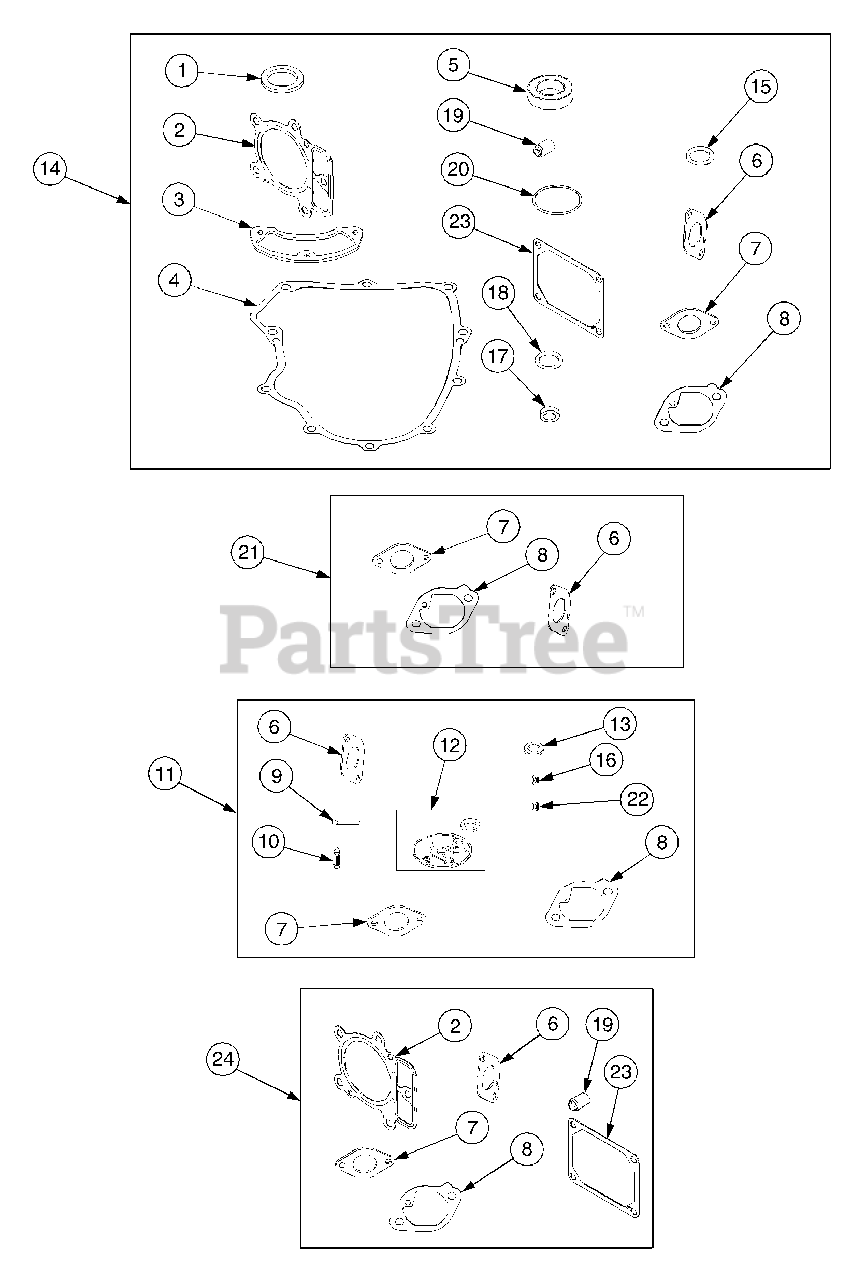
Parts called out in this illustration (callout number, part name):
1	Seal, Oil
2	Gasket, Cylinder Head
3	Gasket, Breather
4	Gasket, Crankcase
5	Seal, Oil
6	Gasket, Intake
7	Gasket, Intake
8	Gasket, Intake
9	Pin, Float Hinge
10	Valve, Float Needle
11	Kit, Carburetor Overhaul
12	Gasket, Float Bowl
13	Washer, Sealing
14	Set, Engine Gasket
15	Seal, Dipstick Tube
16	Seal, Choke/Throttle Shaft
17	Seal, Governor Shaft
18	Seal, Dipstick/Tube
19	Seal, Valve
20	Seal, O-Ring
21	Gasket Set, Carburetor
22	Seal, Throttle Shaft
23	Gasket, Rocker Cover
24	Gasket Set, Valve
